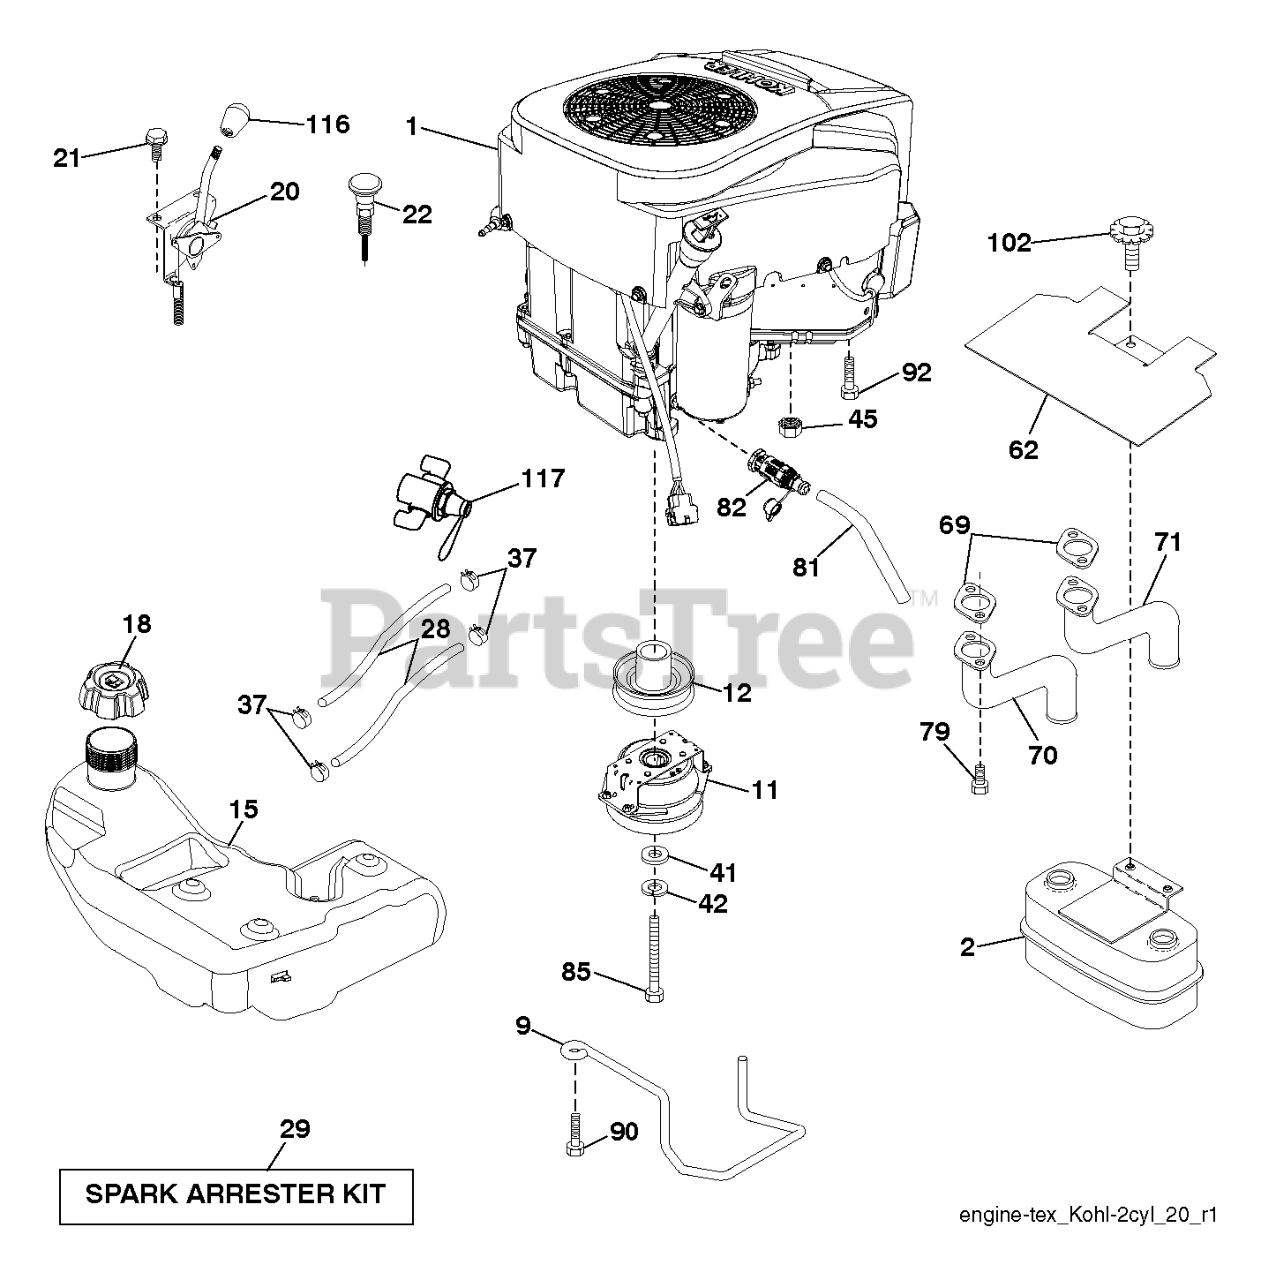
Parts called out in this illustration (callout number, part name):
2	MUFFLER.ASM.TWN.EXTNDED.DFLCTR
9	KEEPER BELT ENGINE
11	CLUTCH MZ ZTR GT.48/54"1.125"
12	PULLEY ENGINE
15	RP_TANK.ASSY.4.GAL.2.PORT.EPA
18	FUEL CAP
18	CAP ASSY FUEL 3" GRAY
20	THROTTLE.KOHL.PRO.#88PAD_46"
21	SCREW.#10X.750
22	CONTROL.CHOKE.ERGO.PUSH-IN.BLA
28	LINE.FUEL.64"REAR.EMIS
29	KIT.SPARK ARRESTOR 794945 B&S
37	HOSE CLAMP
42	LOCKWASHER
45	NUT
62	SHIELD.HEAT.MUFFLER
69	GASKET.EXHAUST.KOHL.CV18-CV26
70	PIPE.EXHAUST.LH.CV18/20
71	PIPE.EXHAUST.RH.CV18/20
79	SCREW.SOCKET HD.5/16-1
81	TUBE, DRAIN OIL ASM.
82	VALUE.OIL.DRAIN
85	BOLT HEX 7/16-20 X 3.75 GR. 5
90	SCREW 3/8-16X1
92	SCREW 3/8-16X1
102	SCREW
116	RP KNOB SOFT TOUCH
117	VALVE FUEL RESERVE
